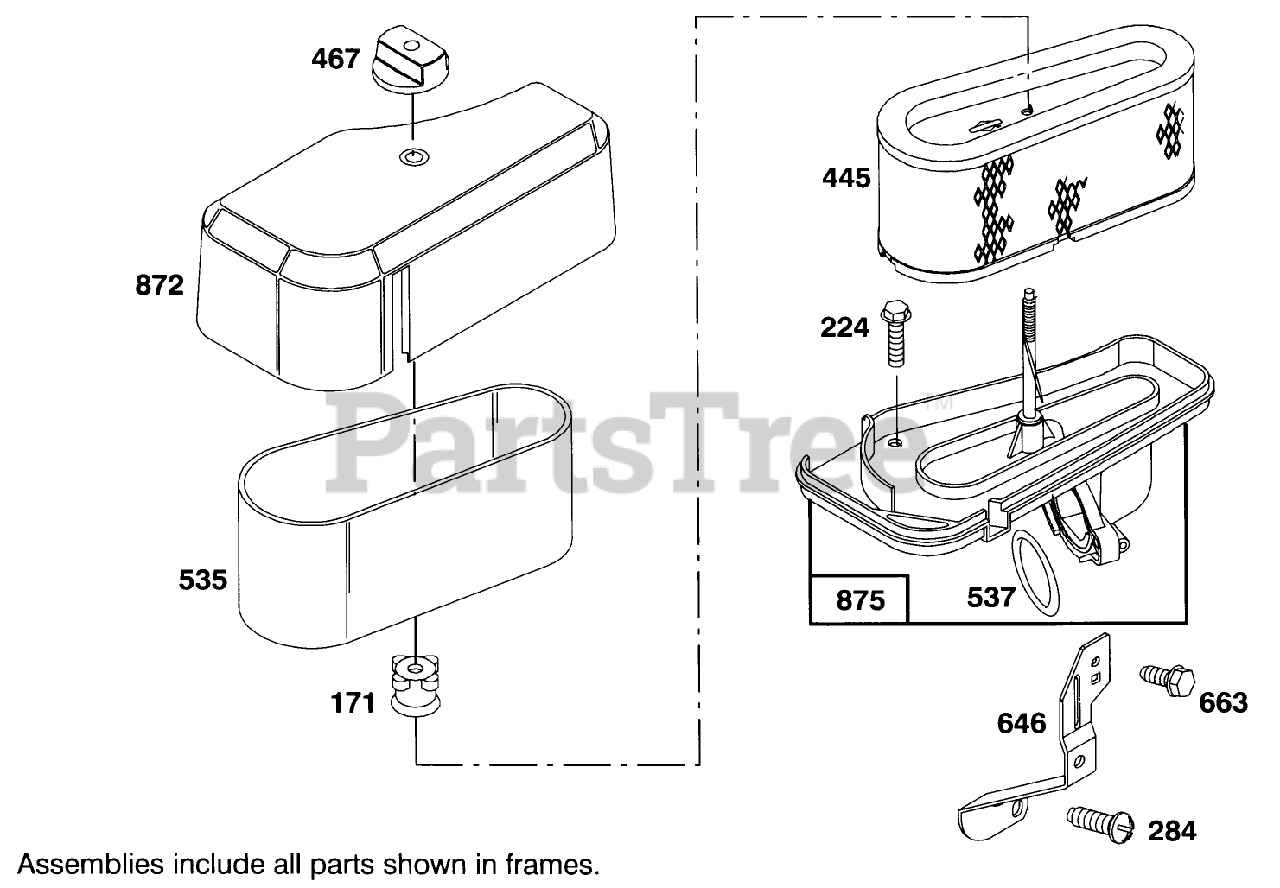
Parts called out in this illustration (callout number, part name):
224	Screw-Sem
284	Screw-Pan Head
445	Filter-Air
535	Filter-Air
537	O-Ring
646	Brace-Air Cleaner
663	Screw
872	Cover-Air Cleaner
875	Base-Air Cleaner
